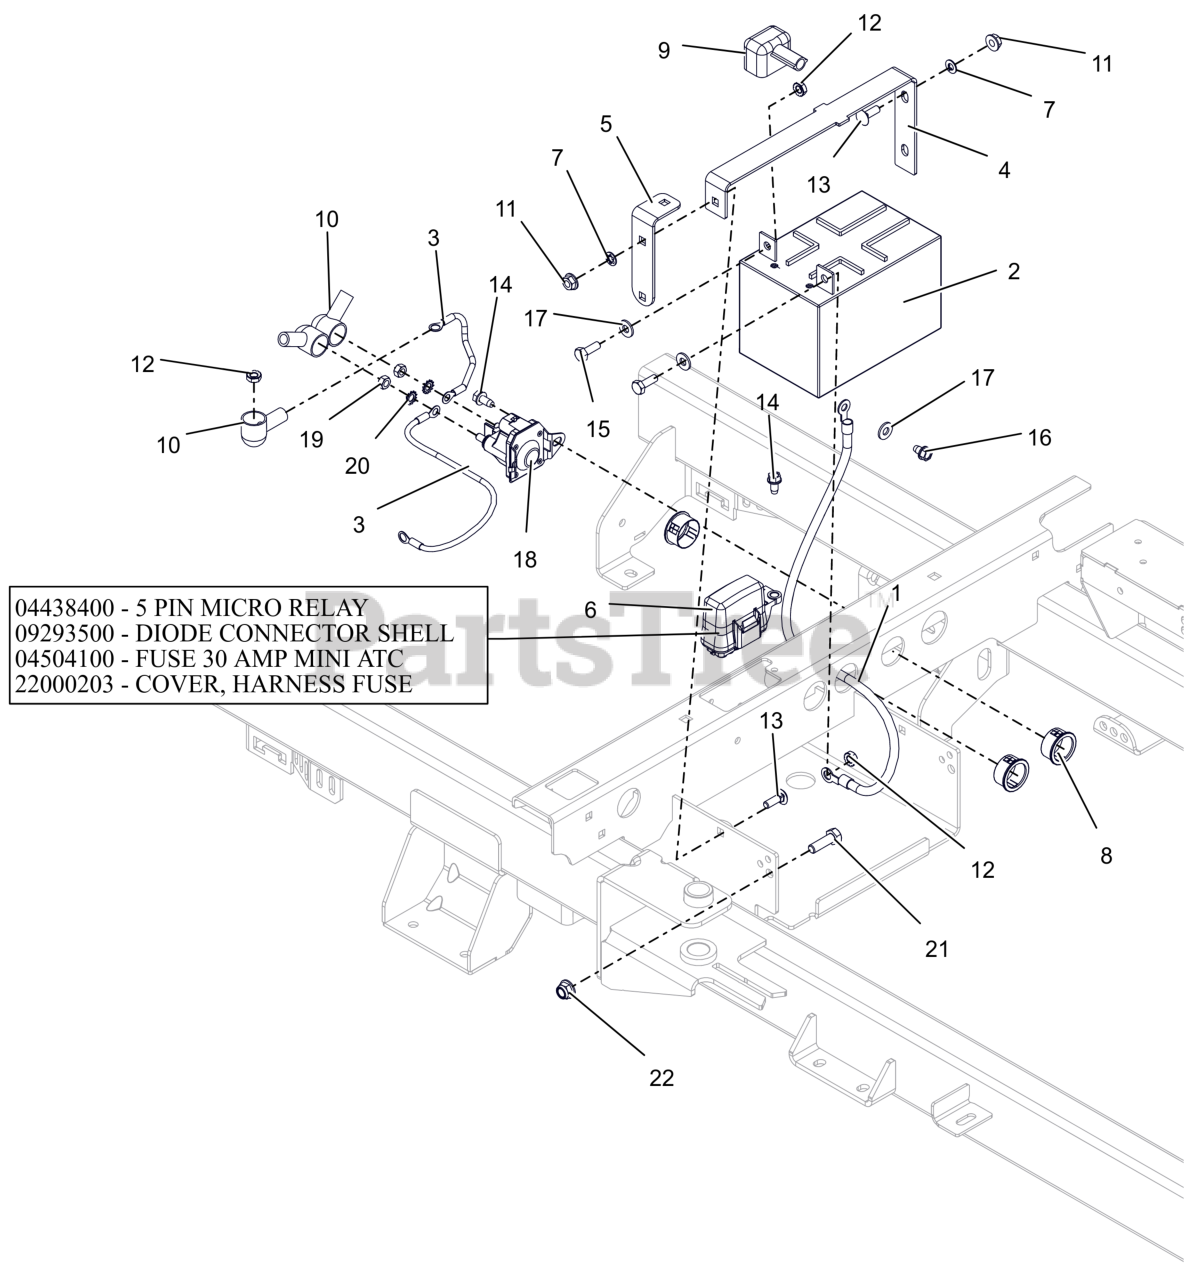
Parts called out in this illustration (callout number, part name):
1	CABLE-NEGATIVE BATTERY 24.00"
2	BATTERY, 12V 12A-190CCA
3	CABLE,POS W/2 1/4 RING 15.0 LG
4	BRKT, BATTERY HOLD-DOWN
5	BRKT, BATTERY HOLD DOWN
6	HARNESS, WIRE-4POS KEY IKON/ZT
6	RELAY,MICRO5 TERML W/RESISTOR
6	DIODE, CONNECTOR SHELL
6	FUSE,30 AMP MINI-ATC
6	COVER, FUSE
7	NUT-PUSH .25X.50 O.D.
8	BSHG, PANEL SNAP .937X1.11X.56
9	INSULATOR
10	BOOT, EYELET TERMINAL
11	NUT-LK-TOP-FLG .250-20 GF ZCC
12	NUT-KEPS .250-20 ZCC
13	BLT, RHSN .25-20X.750 G5 ZCC
14	SCR-TAP .25-20X.50 HWH ZCC
15	BLT, HEX .25-20X.75 G5 ZCC
16	SCR,TAP .25-20X.375 HWH TR ZCC
17	WSHR,FLT .281X.625X.065 ZCC
18	SOLENOID, STARTER (SEALED)
19	NUT-STD M6-1.0 ZCC
20	WSHR,LK-EXT.262X.502X.026 ZCC
21	BLT,HEX .31-18X1.00 G5 ZCC
22	NUT,LK-NYL-FLG .31-18 G5ZC120
